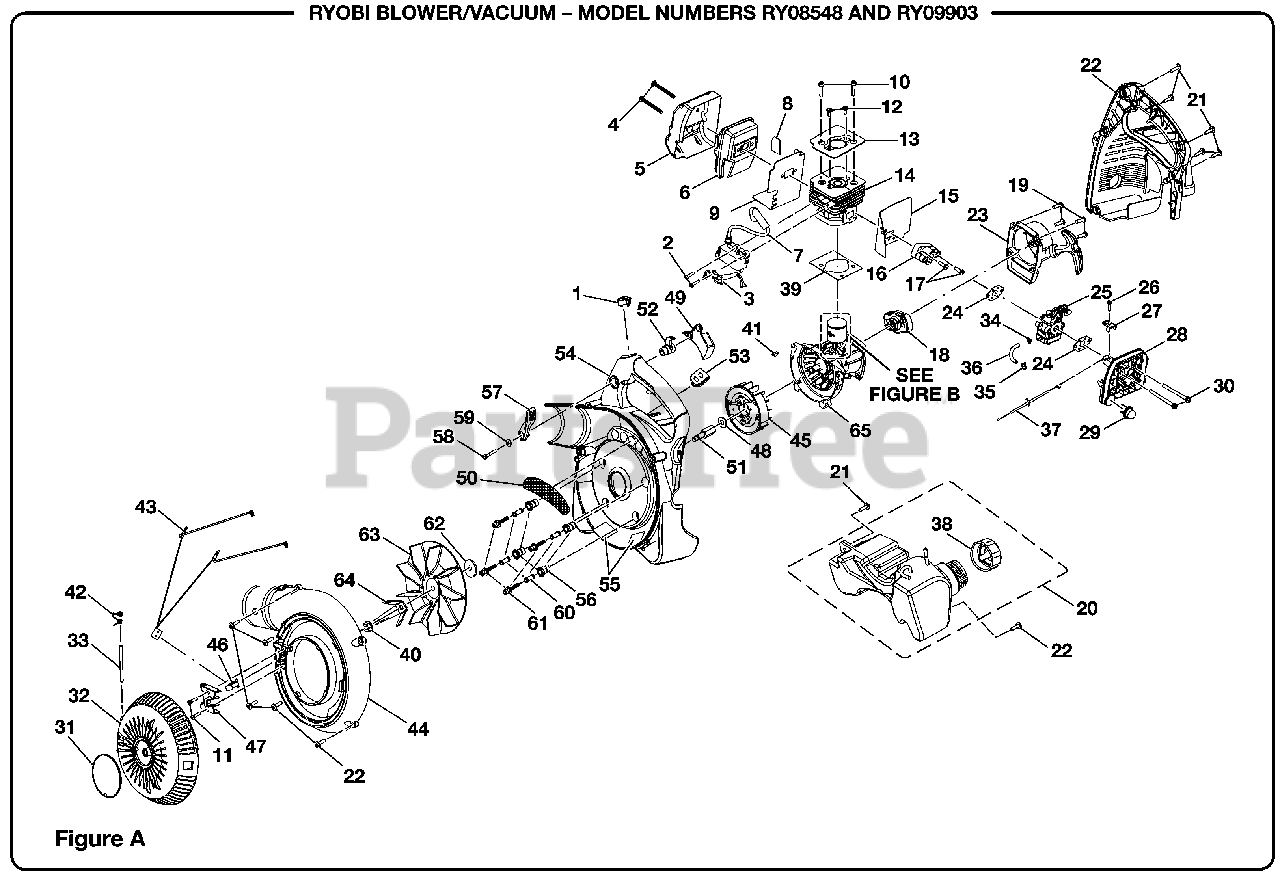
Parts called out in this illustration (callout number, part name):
2	Screw (M4 X 22 mm)
3	Lead Assembly
4	Screw (M5 X 50 mm)
5	Heat Shield
6	Muffler Assembly
7	Coil & Boot Assembly
8	Heat Shield
9	Gasket Muffler
10	Screw (M5 X 22 mm)
11	Screw (M14 X 16.3 mm)
12	Screw & Washer (M5 X 10 mm)
13	Cylinder Plate
14	Cylinder
15	Insulator Gasket
16	Insulator
17	Screw & Washer (M5 X 22 mm)
18	Pulley Assembly
19	Screw (M5 X 16 mm)
20	Fuel Tank Assembly
21	Screw (M14 X 7/8 in.)
22	Engine Shroud Housing
23	Starter Assembly
24	Carburetor Gasket
25	Carburetor (Walbro WYC-8)
26	Screw (M4 X 16 mm Pan Hd.)
27	Throttle Cable Clip
28	Air Box Base
29	Primer Assembly
30	Screw (M5 X 60 mm)
31	Vacuum Door Cover
32	Vacuum Door
33	Hinge Pin
34	Hose Clip (Id 4.9)
35	Hose Clip (Id 2.9)
36	Rubber Tubing
37	Cable Assembly
38	Fuel Cap Assembly
39	Cylinder Gasket
40	Hex Nut w/Retaining Washer
41	Woodruff Key (S43C)
42	Vacuum Door Hinge Spring
43	Vacuum Door Kill Switch
44	Outer Volute Housing
45	Fly-wheel Assembly
46	Kill Switch Activator Lever
47	Vacuum Door Hinge
48	Washer (2 mm)
50	Wire Mesh
51	Crank Shaft Extension
52	Trigger Lock
53	Rubber Grommet
54	Inner Volute Housing
55	Heat Shield
56	Vibration Isolator
57	Cruise Control Lever
58	Screw (M14 X 25 mm)
60	Sleeve Bushing
61	Screw (M5 X 8 mm Cap Hd.)
62	Fan Spacer (Washer)
63	Blower Fan (24.5)
64	Mulcher Blade
65	Crankcase Assembly
